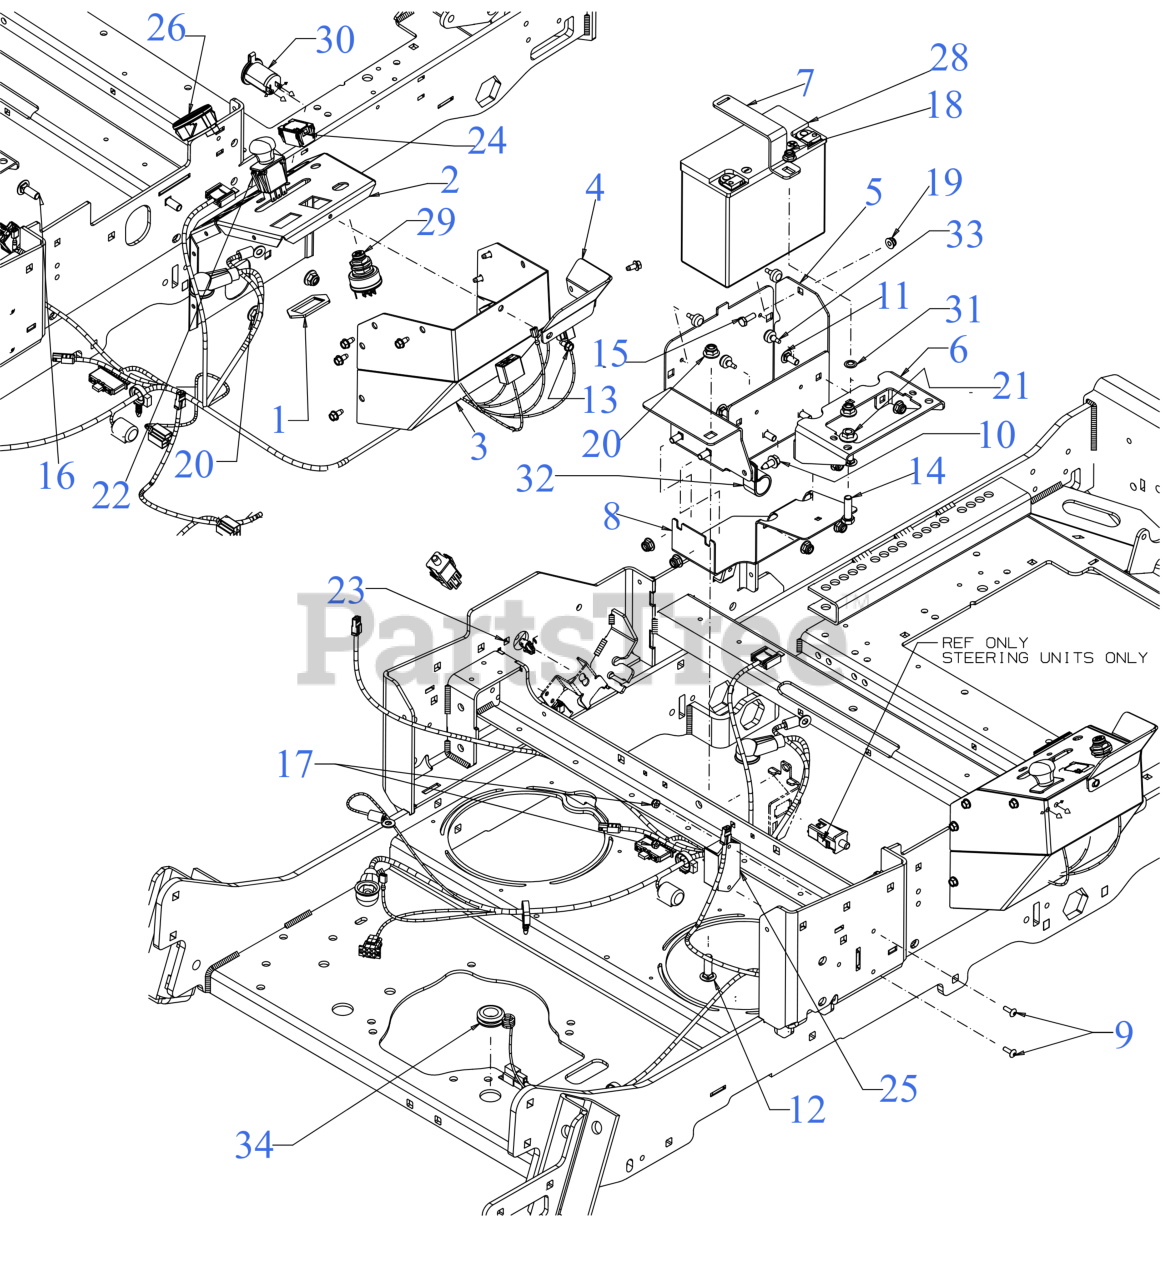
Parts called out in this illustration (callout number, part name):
1	BRACKET-PTO SWITCH
2	CONTROL POD - RH
5	BATTERY MOUNT BRACKET
6	FUSE/RELAY MOUNT BRACKET
7	BATTERY SUPPORT BRACKET
8	HOSE/BELT COVER
9	SCREW #10-24 x .62
10	SCREW 5/16-18 x .750
11	CARRIAGE BOLT 5/16-18 x .75
12	CARRIAGE BOLT 3/8-16 X1.25 GR5
13	SCREW 1/4-20 X.500
14	SCREW 3/8-16 x 1.25 GR5
15	SCREW 1/4-20X.75 GR5
16	CARRIAGE BOLT 3/8-16 x 1.00 GR5
18	FLANGE LOCK NUT 5/16-18
19	FLANGE LOCK NUT
21	FLANGE LOCK NUT
22	PTO SWITCH (BLACK KNOB) TEXT SYM
23	3 POLE SWITCH ( NC-NO-NO)
25	CONTROL PANEL
26	DUAL FUEL GAUGE
27	MAIN HARNESS
28	BATTERY (300 CCA)
29	KEY SWITCH
29	PRO-Z KEY SET
30	POWER RECEPTICAL
32	HOSE CLAMP 1.0"
33	BUMPER, .62 DIA x .3
34	RUBBER GROMMET
